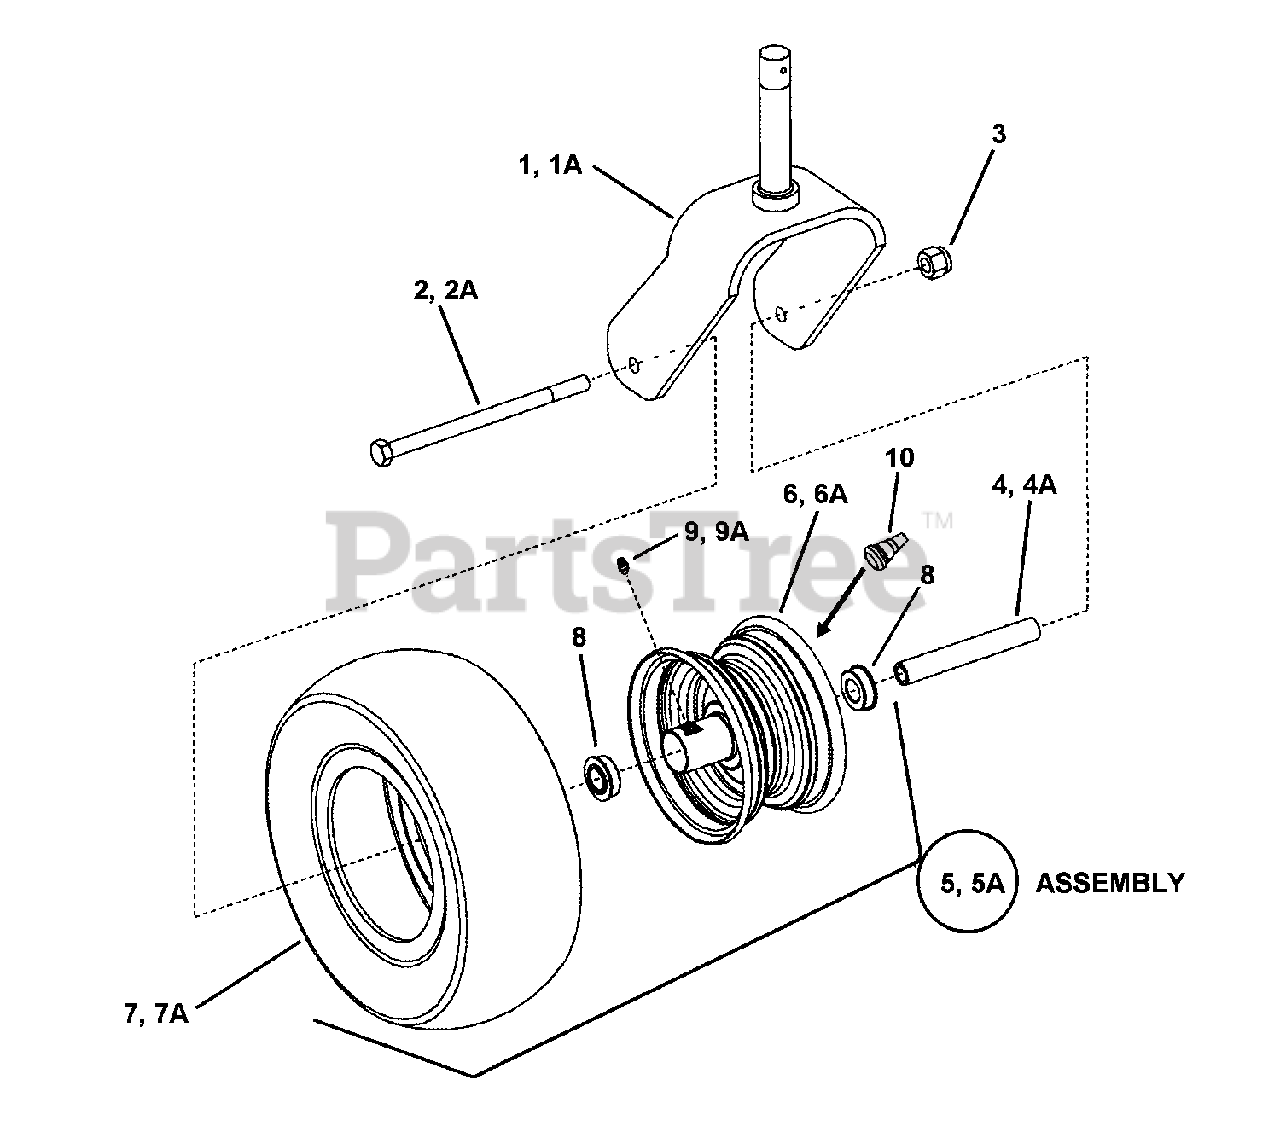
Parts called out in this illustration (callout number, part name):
1	WELDMENT, Caster Yoke
1A	WELDMENT, Caster Yoke, 7-1/4" Wide
2	BOLT, HEX, 1/2-13 X 7, GD 8, YZ
2A	SCREW, 1/2-13 x 9-1/2" Hex Head Cap, GR5
3	NUT,1/2-13 Nyloc
4	SPACER, Bearing, 5.29" Long
4A	SPACER, Bearing, 7.29" Long
5	ASSY, Tire & Wheel (Incl. items 6 thru 10)
5A	ASSY, Tire & Wheel (Incl. items 6A, 7A, 8, 9A & 10)
6	WELDMENT, Wheel Hub & Rim
6A	WELDMENT, Wheel Hub & Rim
7	TIRE, 13 x 5.06 4 Ply Slick
7A	TIRE, 13 x 6.5-6 4 Ply Slick
8	BEARING, .750 Heim
9	FITTING, Lube
9A	FITTING, Lube, 1/4-28 Thread
10	VALVE STEM, Air
